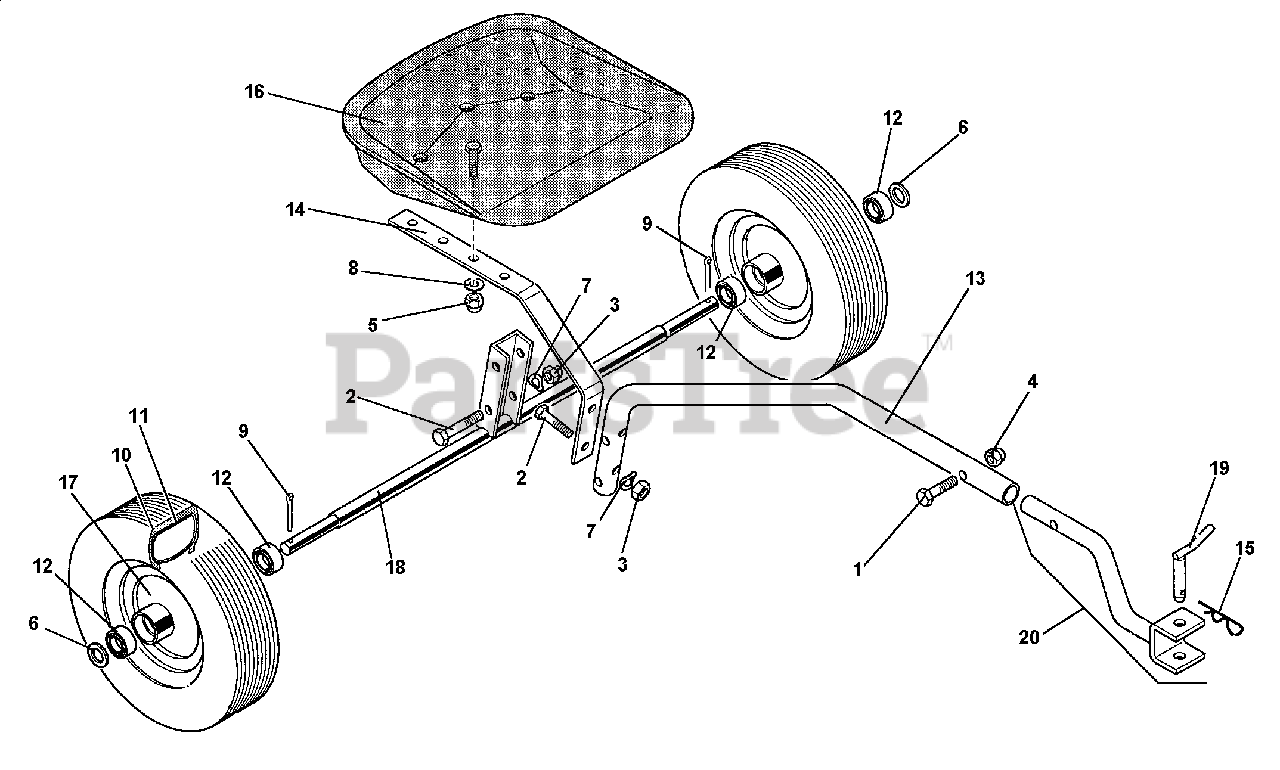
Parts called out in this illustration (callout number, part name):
1	Screw, M10 X 60
2	Screw, M10 X 65
3	Nut, M10
4	Nut, Self Locking M10
5	Nut, Self Locking M12
6	Washer, Flat
7	Washer, Lock 10.5
8	Washer, Lock M13
9	Cotter Pin
11	Tube 4.00 X 8
12	Bushing
14	Seat Spring
16	Padded Seat
17	Sulky Wheel
19A	Pin - 700 Series Tractors
19B	Pin - 800/900 Series Tractors
20A	Curved Coupler - 700 Series Tractors
20B	Curved Coupler - 800 Series Tractors
20C	Curved Coupler - 900 Series Tractors
